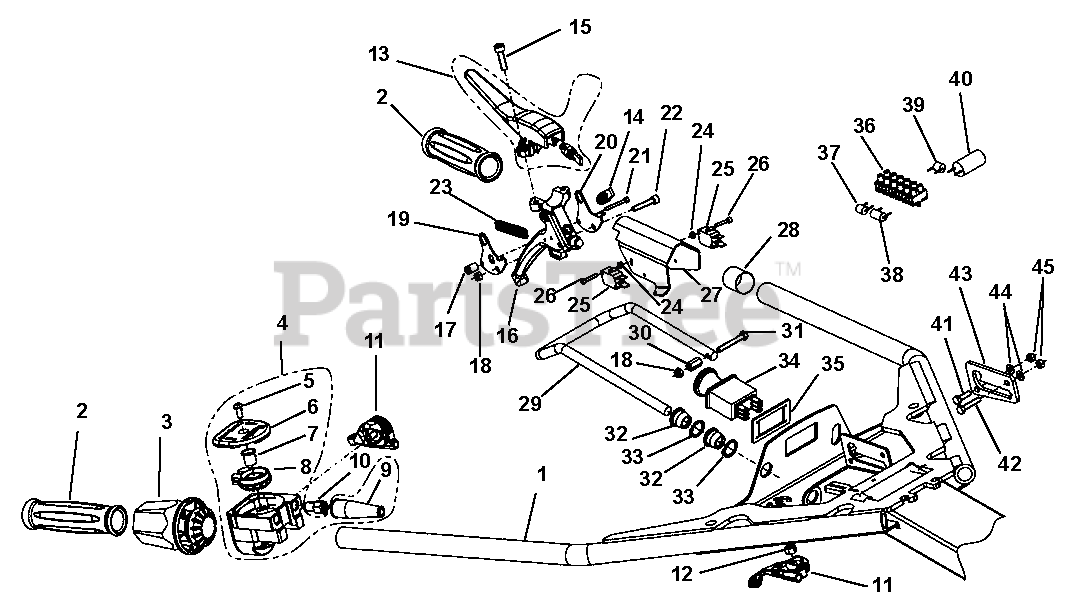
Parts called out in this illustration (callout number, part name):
1	Handlebar
2	Handle, Rubber
3	Bushing, Grip
4	MF Control Unit CPL, (Includes items 5 – 8)
5	Screw, M5 x 12/ 10.9
7	Bushing
8	Bevel Wheel with Cam
10	Nipple, Screwed
11	Assembly, Throttle Lever
12	Nut, Lock D985 M6
13	Lever, Emergency
15	Screw, D912 M6 x 22
16	Lever, Control
18	Nut, Lock
19	Tracer Plate
20	Tracer Plate
21	Screw, D912 M3 x 25
22	Screw, D912 M5 x 25
23	Spring, Tension
24	Nut, Lock D985 M3
25	Switch, Micro
26	Screw, D912 M3 x 16
28	Shrinkdown Tubing, RNF100 1 TYP1
29	Lever, Locking
30	Nut, Hex DIN 6334 M5 x 15
31	Bolt, Hex D933 M5 x 35
34	Switch, PTO
35	Front Screen
36	Clamping Ledge
37	Resistor, 15 Ohm 2W
38	Resistor, 2.7 Ohm 13W
40	Condenser
41	Bolt, Hex D933 M5 x 16
42	Bolt, Hex D933 M5 x 25
43	Guide Sheet Metal
44	Washer M5
45	Nut, Hex D934 M5
